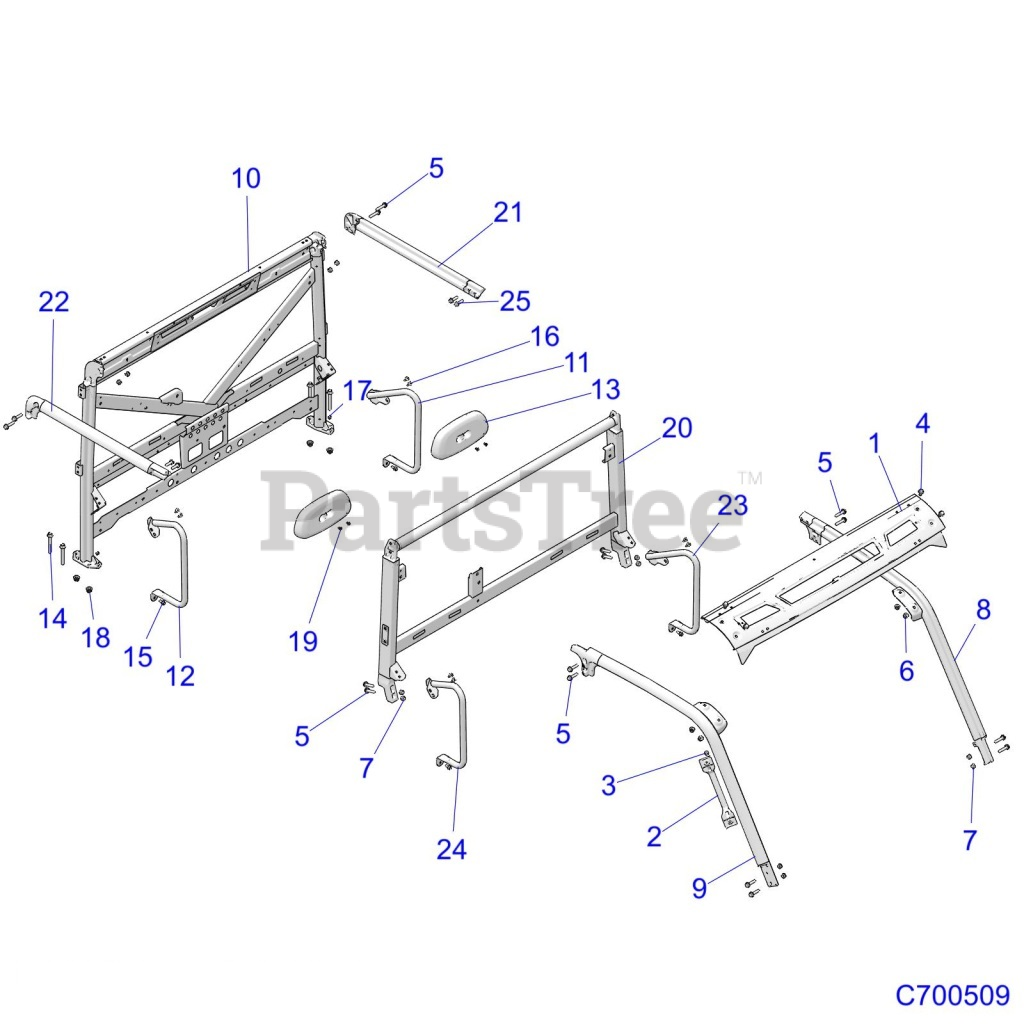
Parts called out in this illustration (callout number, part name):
1	PLATE-WNDSHLD MNT,UPR,BLK
2	HANDLE-GRAB,ROPS,BLK
3	BOLT-M8X1.25X20,HXFLG,TAP/R-OD
4	SCR-HXFL-M10X1.5X20 10.9 RIE P
5	SCR-HXFL-M10X1.5X45 10.9 RIE
6	NUT-HXFL-M10X1.5 8 ZB3 NYL
7	NUT-HEX-M10X1.5 10 ZB3 NYL
8	WELD-CAB FRAME, FRT, LH, BLK
9	WELD-CAB FRAME, FRT, RH, BLK
10	WELD-CAB FRAME,REAR,M.BLK
11	WELD-BOLSTER,LH, M.BLK
12	WELD-BOLSTER,RH,M.BLK
13	HEADREST-BLK
14	SCR-HXFL-M12X1.75X90 10.9 ZPC
15	SCR-HXFL-M8X1.25X20 8.8 ZOD P3
16	SCR-TXTH-M6X1.0X25 RIE
17	NUT-HEX-M8X1.25 10 P&O
18	NUT-HXFL M12X1.75 NYLOC ZOD
19	RIVET(50)
20	WELD-CAB FRAME, CTR, M. BLK
21	WELD-CAB FRAME, REAR, LH, BLK
22	WELD-CAB FRAME, REAR, RH, BLK
23	WELD-BOLSTER,FRONT,LH,M.BLK
24	WELD-BOLSTER,FRONT,RH,M.BLK
25	SCR-M10X1.50X35 HX/FL-Y/D
